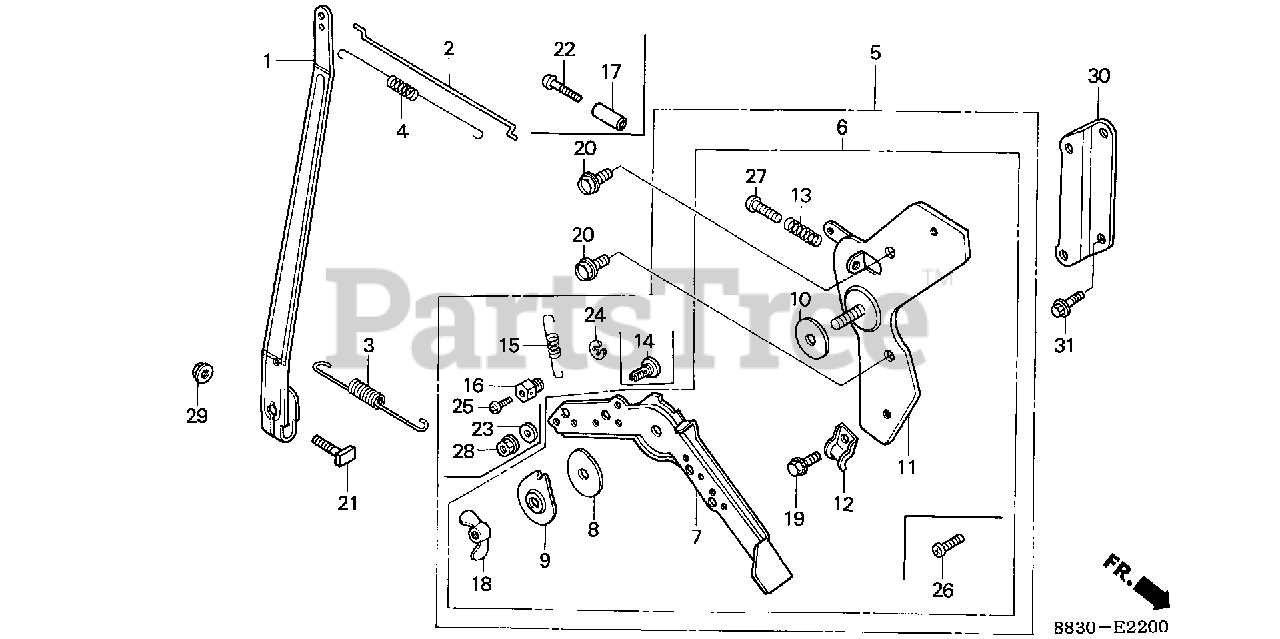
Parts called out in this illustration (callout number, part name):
1	ARM, GOVERNOR
2	ROD, GOVERNOR
3	SPRING, GOVERNOR
4	SPRING, THROTTLE RETURN
5	CONTROL ASSY. Use from Engine SN 2327377.
6	CONTROL ASSY.
7	LEVER, CONTROL
7	LEVER, CONTROL Use from Engine SN 2327377.
8	SPRING, LEVER
8	SPRING, LEVER Use from Engine SN 2327377.
9	WASHER, CONTROL LEVER
9	WASHER, CONTROL LEVER Use from Engine SN 2327377.
10	SPACER, CONTROL LEVER
10	SPACER, CONTROL LEVER Use from Engine SN 2327377.
11	BASE, CONTROL LEVER Use up to Engine SN 1094580.
11	BASE, CONTROL LEVER
11	BASE, CONTROL LEVER Use from Engine SN 2327377.
12	HOLDER, CONTROL CABLE
12	HOLDER, CONTROL CABLE Use from Engine SN 2327377.
13	SPRING, CONTROL ADJUSTING
13	SPRING, CONTROL ADJUSTING Use from Engine SN 2327377.
15	SPRING, CABLE RETURN Use from Engine SN 2327377.
16	HOLDER, WIRE Use from Engine SN 2327377.
18	WINGNUT (6MM) Use up to Engine SN 1094580.
18	WINGNUT (6MM) Use from Engine SN 2327377.
19	BOLT, FLANGE (5X10)
19	BOLT, FLANGE (5X10) Use from Engine SN 2327377.
20	BOLT, FLANGE (6X12) (CT200)
21	BOLT, GOVERNOR ARM
24	CIRCLIP (5MM) Use from Engine SN 2327377.
25	SCREW, PAN (4X6) Use from Engine SN 2327377.
26	SCREW, PAN (5X10) Use up to Engine SN 1575771.
27	SCREW, PAN (5X22)
27	SCREW, PAN (5X22) Use from Engine SN 2327377.
28	NUT, FLANGE (6MM)
